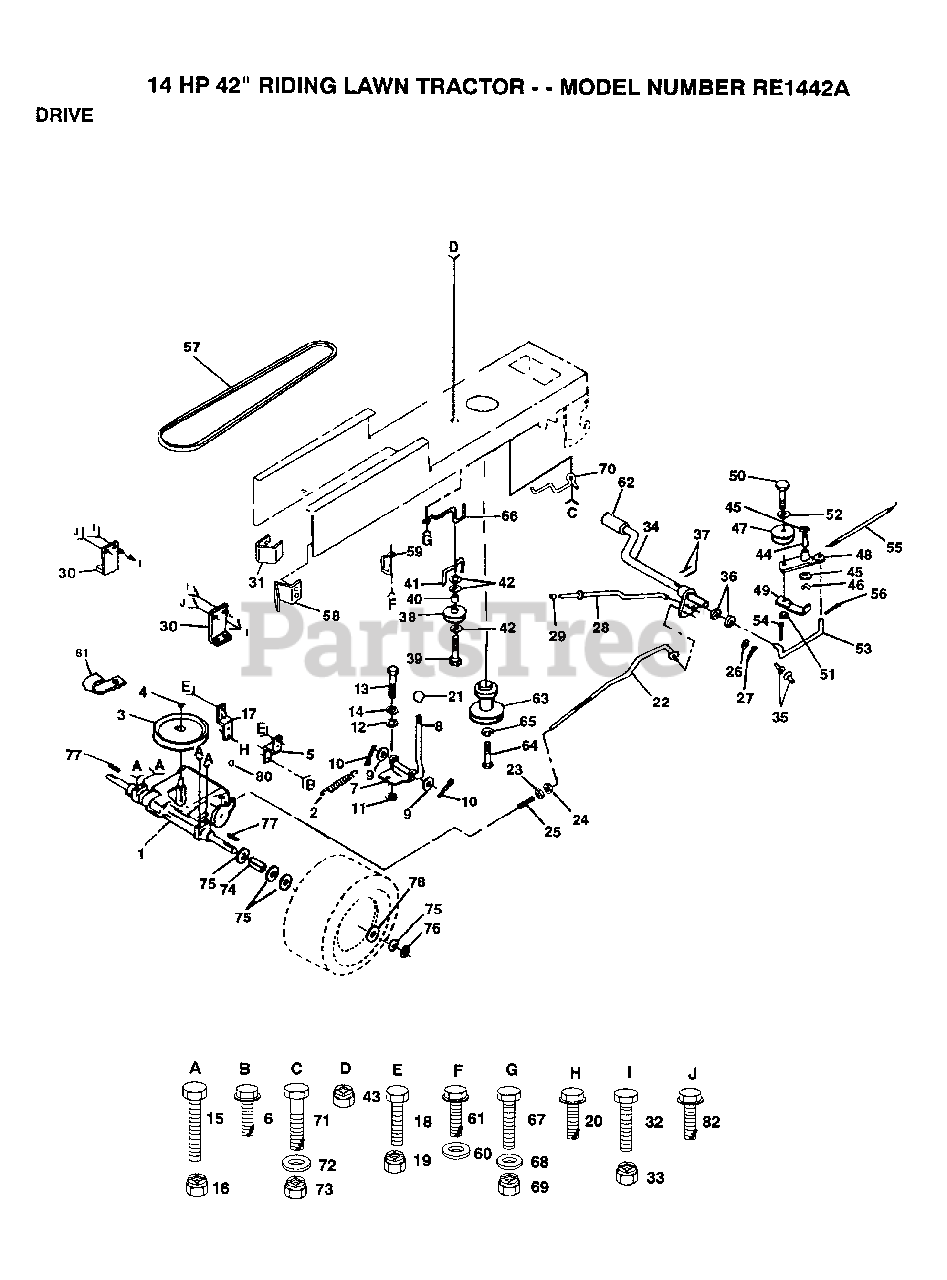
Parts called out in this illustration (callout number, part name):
3	PULLEY TRANS
5	STRAP TORQUE
6	SCREW
8	SHIFT ROD
9	WASHER
10	PIN COTTER 1/8
11	WASH-SHFT PLT LT
12	WASHER LT
14	LOCKWASHER
15	BOLT
17	STRAP TORQUE
20	SCREW
21	CONTROL KNOB LT
22	BRAKE ROD
23	NUT
24	NUT
25	SPRING ROD LT
26	WASHER
27	COTTER PIN
28	PARKING BRAKE ROD
30	TRANSAXLE MTG BKT
31	"KEEPER,BELT LH T"
32	BOLT
35	NYLON BEARING
36	WASHER LT
38	PULLEY.IDLER.FLAT
39	BOLT
40	SPACER T
41	BELT KEEPER LT
42	WASHER
44	"LY, BEARING"
45	WASHER LT
46	KLIP RING
48	ARM IDLER
49	RETAIN BELT
52	WASHER
53	"LINK, CLUTCH T"
54	COTTER PIN
55	"SPRING, RETURN LT"
56	COTTER PIN
58	"KEEPER,BELT RH T"
60	WASHER
61	SCREW
62	PEDAL COVER T
64	BOLT
65	LOCKWASHER
66	KEEPER.BELT.ENG.L
67	BOLT
68	WASHER
70	KEEPER BELT ENG
71	BOLT
72	WASHER
74	SPACER LT
75	WASHER
76	E-RING LT
77	SQUARE KEY
78	WASHER
81	CLIP T
82	SCREW
